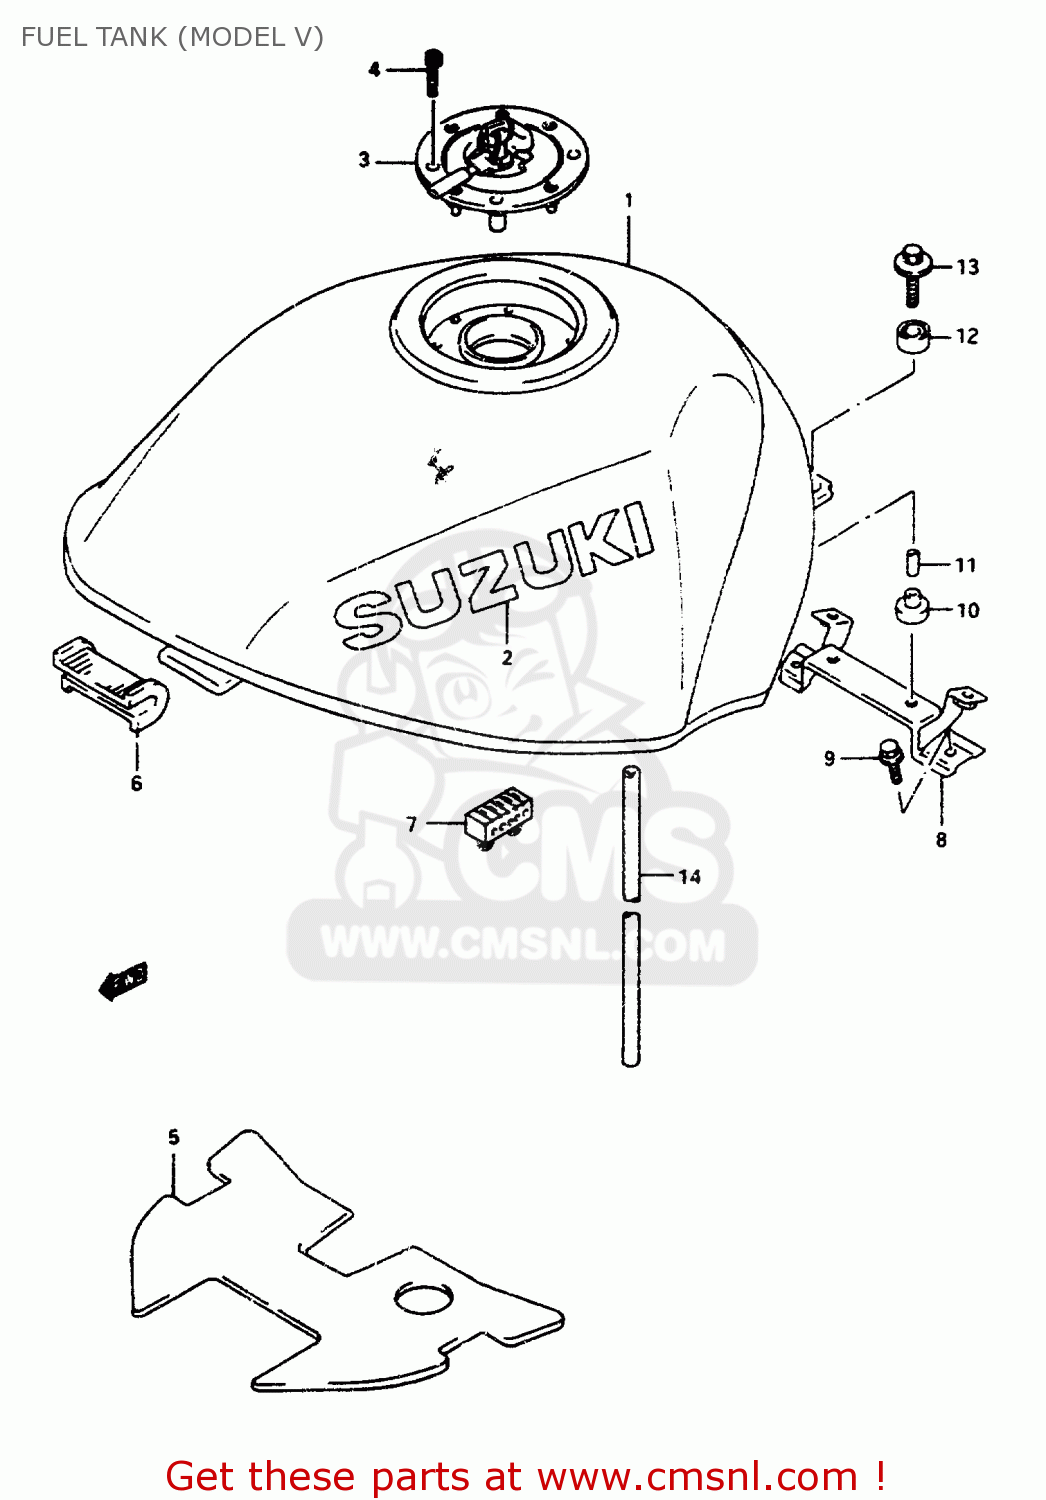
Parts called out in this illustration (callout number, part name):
1	TANK ASSY,FUEL (GREEN)
2	EMBLEM,FUEL TANK
3	CAP SET,FUEL TANK
4	BOLT(5X20)
5	SHIELD,FUEL TANK HEAT NO.1
6	CUSHION,FUEL TANK FR
7	CUSHION,SEAT(40X20X15)
8	BRACKET,FUEL TANK RR
9	BOLT
10	CUSHION
11	SPACER
12	CUSHION
13	BOLT
14	HOSE(7X10.2X600)
